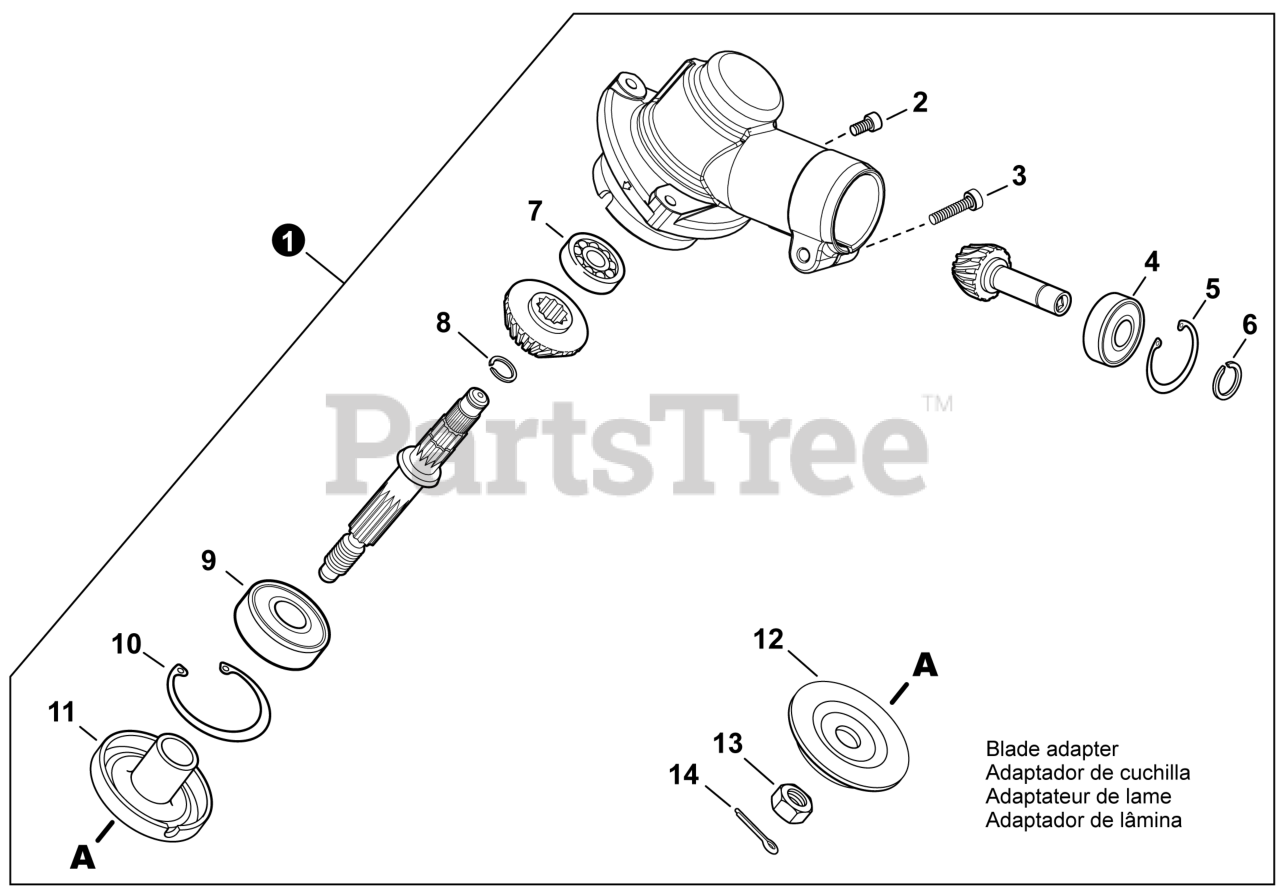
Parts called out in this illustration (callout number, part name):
1	GEAR CASE ASSY
2	BOLT, TORX 5x12
3	BOLT, TORX 5x25
4	BEARING, BALL 609ZA
5	RING, SNAP 24
6	RING, SNAP 9
7	BEARING, BALL 609A
8	RING, SNAP 12
9	BEARING, BALL 6201 2RS
10	RING, SNAP 32
11	PLATE, ADAPTOR - UPPER
12	PLATE, ADAPTOR - LOWER
14	PIN, COTTER 2x22
